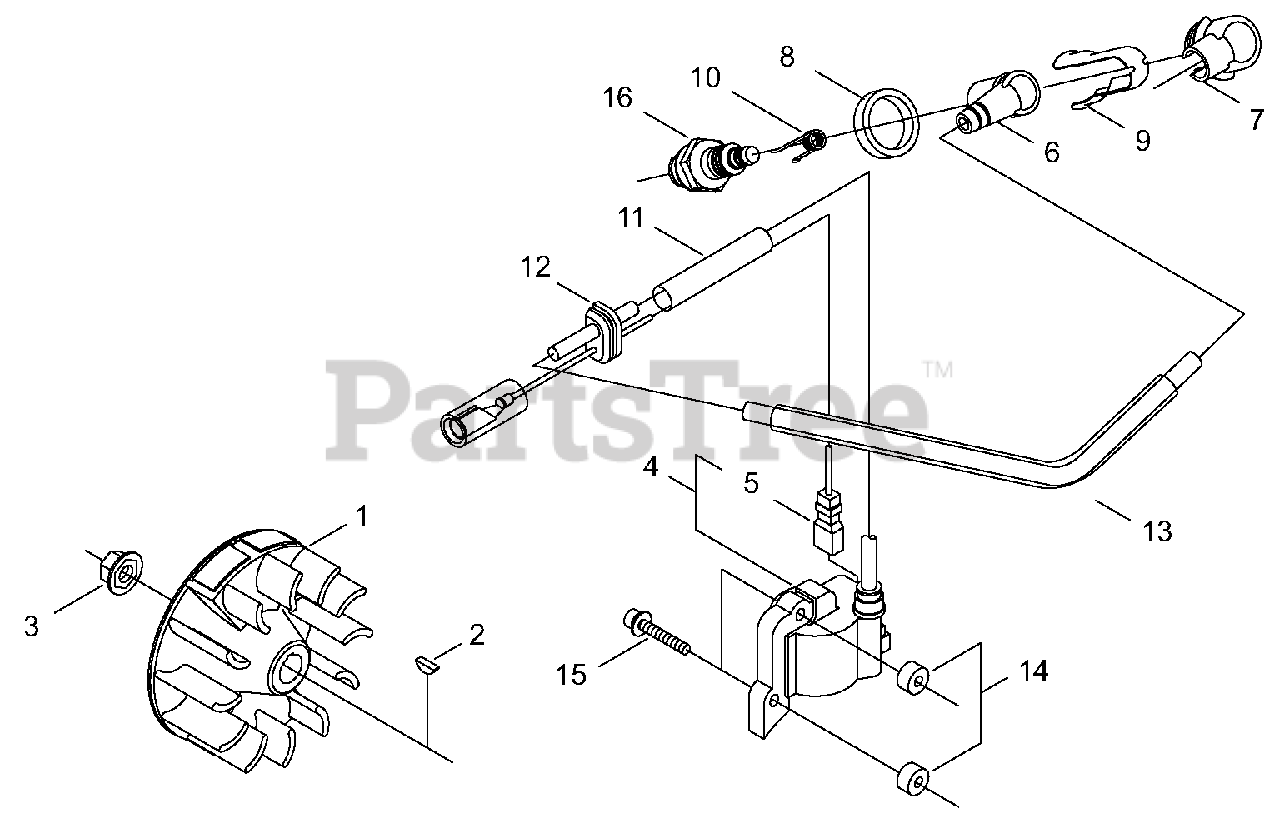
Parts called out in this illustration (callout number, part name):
1	FLYWHEEL
2	KEY, WOODRUFF 3×10
3	NUT M8
4	COIL ASSY, IGNITION
5	LEAD
6	CAP, SPARK PLUG
7	COVER, CAP
8	SEAL, SPARK PLUG
9	SHIELD
10	TERMINAL, SPARK PLUG
11	TUBE, IGNITION COIL
12	GROMMET
13	TUBE, INSULATOR
14	INSULATOR 4.2×11×6
15	BOLT M4×26
16	SPARK PLUG - BMR6A
